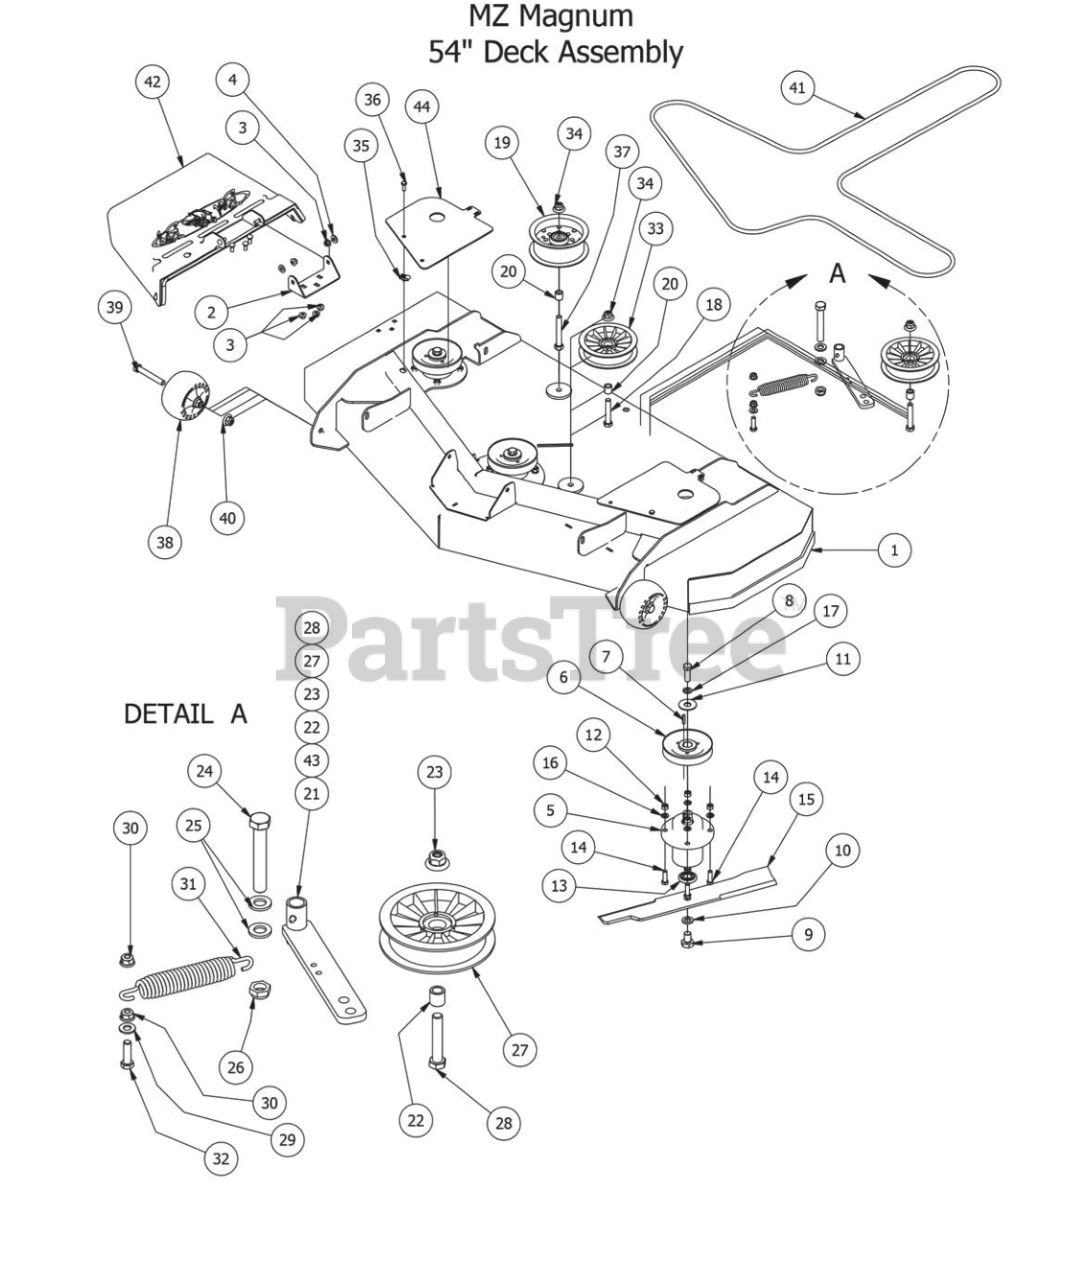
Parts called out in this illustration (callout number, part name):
1	54 MZ Deck
2	Chute Hanger 48 MZ
3	5/16" Nylon Flange Nut
4	.360 ID Plastic Washer
6	MZ Deck Pulley
7	3/16 x 1 Square Key
8	1/2"-20 x 1 1/2 - Grade 5 Fine Thread Bolt
9	5/8" x 1 1/2" Grade 8 Bolt
10	5/8" Lock Washer
11	Type B Plain Washer
12	3/8" Hex Nut
13	Spindle Bearing
14	3/8" x 1 1/4" Hex Bolt
15	54" MZ Fusion Blade
16	3/8" Lock Washer
17	1/2" Lock Washer
18	1/2" x 2 3/4" Hex Bolt
19	5 3/4 flat idler-32fI-92-008
20	3/4 OD x 1/2 ID x 3\4 Length
21	Deck Idler 2009 AOS
22	3/4 OD x 1/2 ID x 3\4 Length
23	1/2-13 Nylon Flange Nut-Orange
24	5/8" x 4" Hex Bolt
25	.635 ID Plastic Washer
26	5/8" Nylock (1/2 Jam)
27	Plastic Idler Pulley
28	1/2" x 2 3/4" Hex Bolt
29	3/8" Flat Washer
30	3/8" Nylock Flange Nut
31	Deck Idler Spring 2009
32	3/8" x 1 1/4" Hex Bolt
33	Plastic Idler Pulley
34	1/2-13 Nylon Flange Nut-Orange
35	1/4-20 Cage Nut
36	1/4" x 3/4" Hex Bolt
37	1/2-13 x 3 1/2 GR 5 Hex Bolt
38	Deck Wheel
39	1/2 x 3 1/2 Flange Bolt Grade 8
40	1/2-13 Nylon Flange Nut-Orange
41	B 138 Belt 54" MZ Magnum
42	MZ Discharge Assembly
43	MZ Deck Idler Assembly (Components 22,23,27,28,43,)
44	2014 54" MZ Mag Pulley Cover
